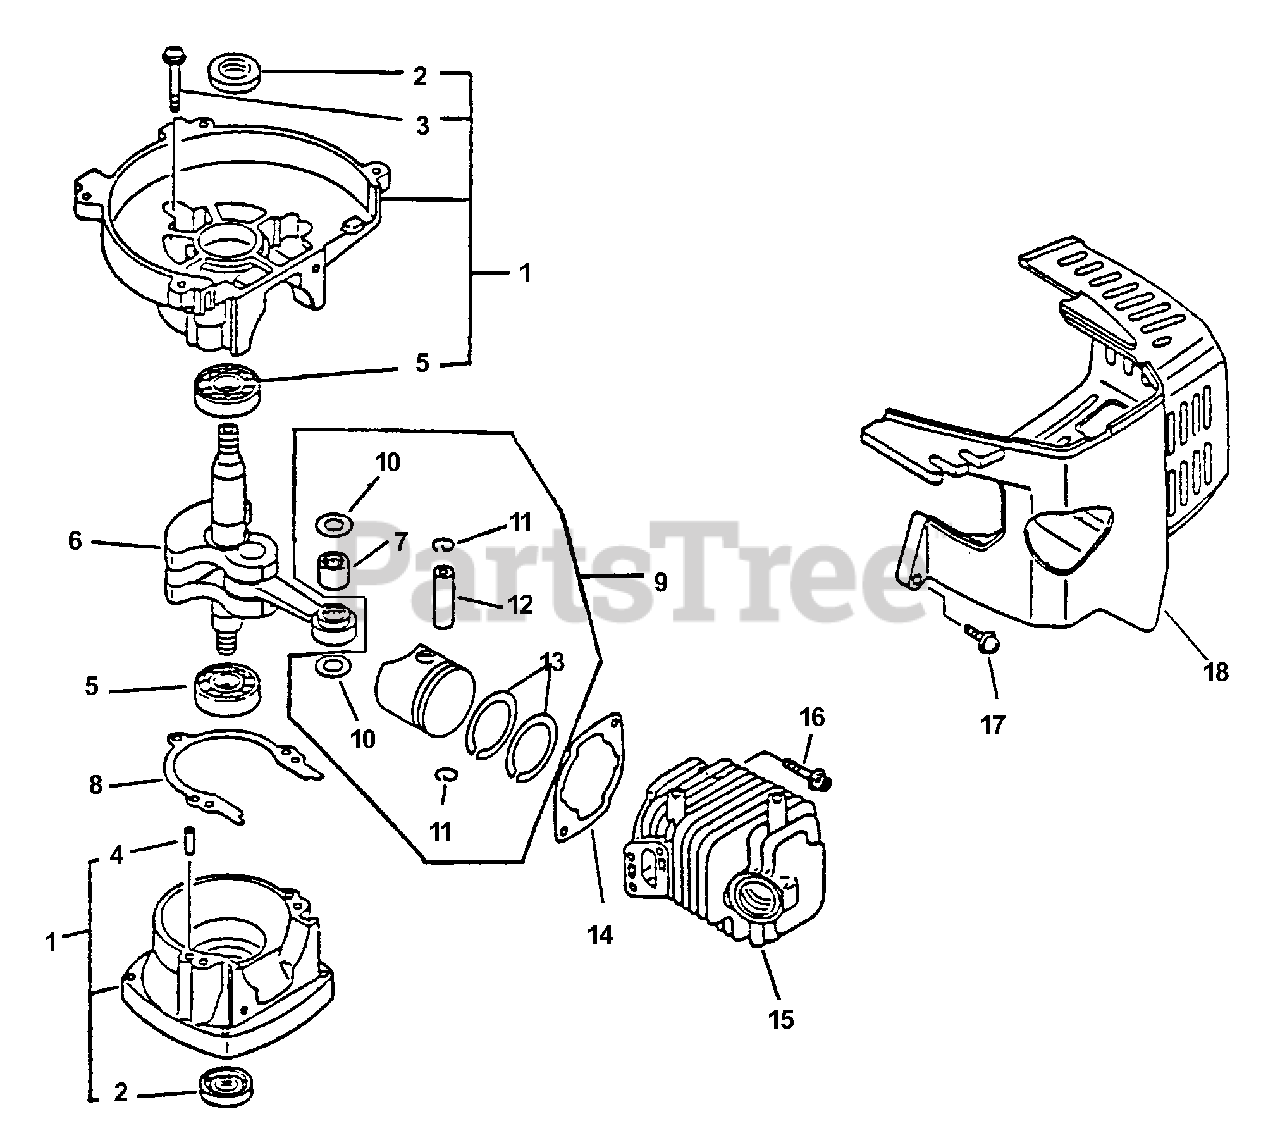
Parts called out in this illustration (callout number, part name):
1	CRANKCASE KIT
2	SEAL, OIL 12
3	BOLT 5×28
4	PIN, LOCATING 4
5	BEARING, BALL - 6201 C3
6	CRANKSHAFT ASSY
7	BEARING, NEEDLE
8	GASKET, CRANKCASE
9	PISTON KIT
10	WASHER, THRUST
11	RING, SNAP
12	PIN, PISTON 8
13	RING, PISTON
14	GASKET, CYLINDER
15	CYLINDER
16	BOLT 5×22
17	SCREW 4×22
18	COVER, CYLINDER
